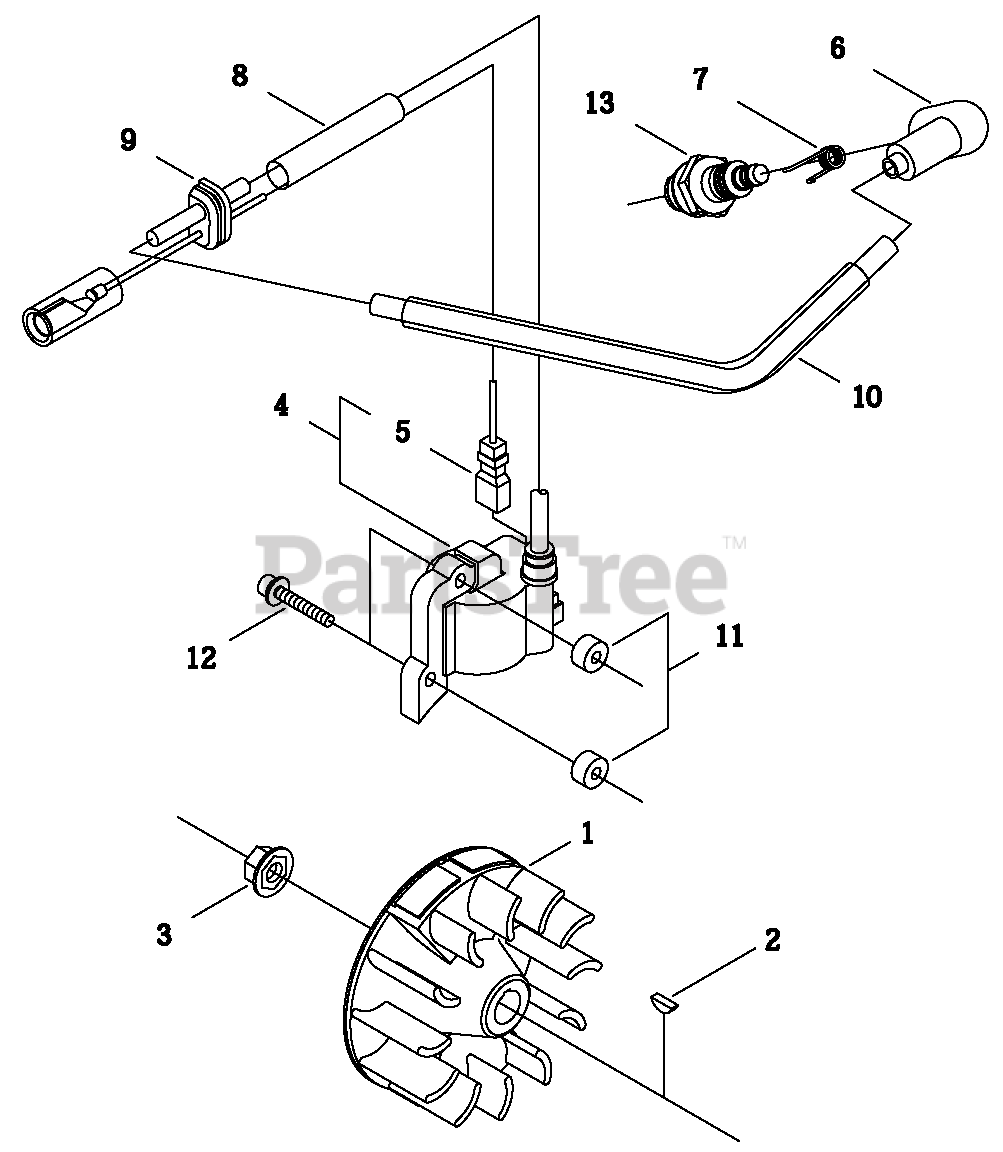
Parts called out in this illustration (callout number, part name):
1	FLYWHEEL
2	KEY, WOODRUFF 3×10
3	NUT M8
4	COIL ASSY, IGNITION
5	LEAD
6	CAP, SPARK PLUG
7	TERMINAL, SPARK PLUG
8	TUBE, IGNITION COIL
9	GROMMET
10	TUBE, INSULATOR
11	INSULATOR 4.2×11×6
12	BOLT M4×26
13	SPARK PLUG - CJ8
